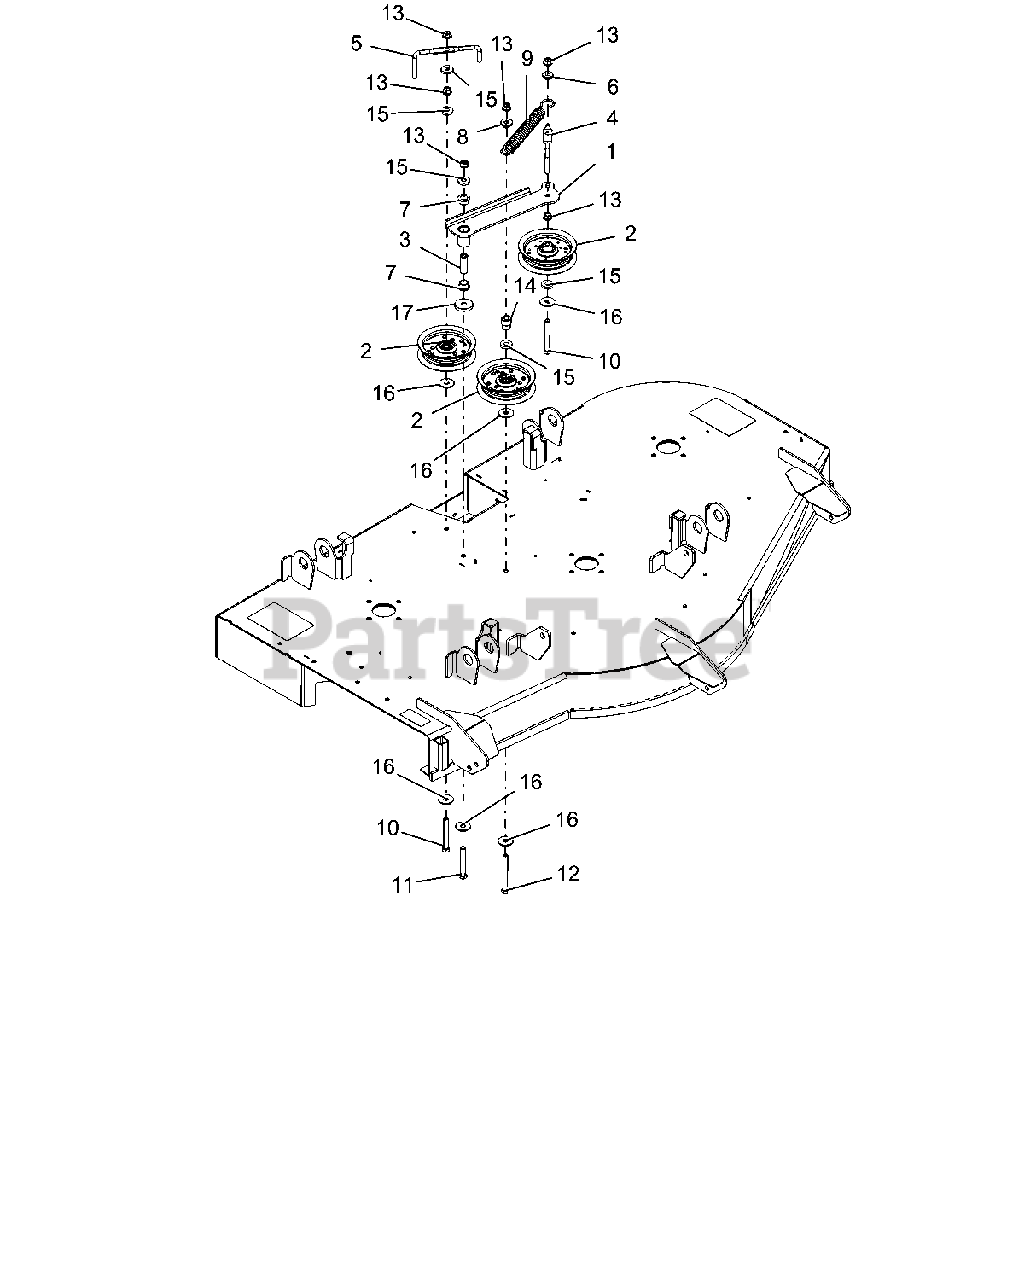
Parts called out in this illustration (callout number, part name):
1	WLDMT, IDLER - 52" IDLER ARM (RED)
2	ASM, IDLER 4"
3	SPCR, .375IDX.625ODX1.66 PM
4	WIREFORM, BELT FINGER-RED
5	FINGER, BELT (RED)
6	BSHG, FLG .385 X .500 X .875 X .406
7	BSHG, FLANGE .625 x .75 x .50 x 1.00
8	BSHG-FLG .385X.500X.875X.31
9	SPRG, EXTENSION
10	BLT-HEX .38-16X3.00 GR5 FTH YWZC
11	BLT-HEX .38-16X2.75 GR5 YWZC
12	BLT-HEX .38-16X3.50 GR5 YWZC
13	NUT, LK-TOP-FLG .38-16 YWZC
14	BUSHING, IDLER
15	WSHR-FL-STL .406X1.00X.188 YWZC
16	WSHR-FL-STL .406X1.25X.10 YWZC
17	WSHR-FL-STL .406X1.50X.245 YWZC
